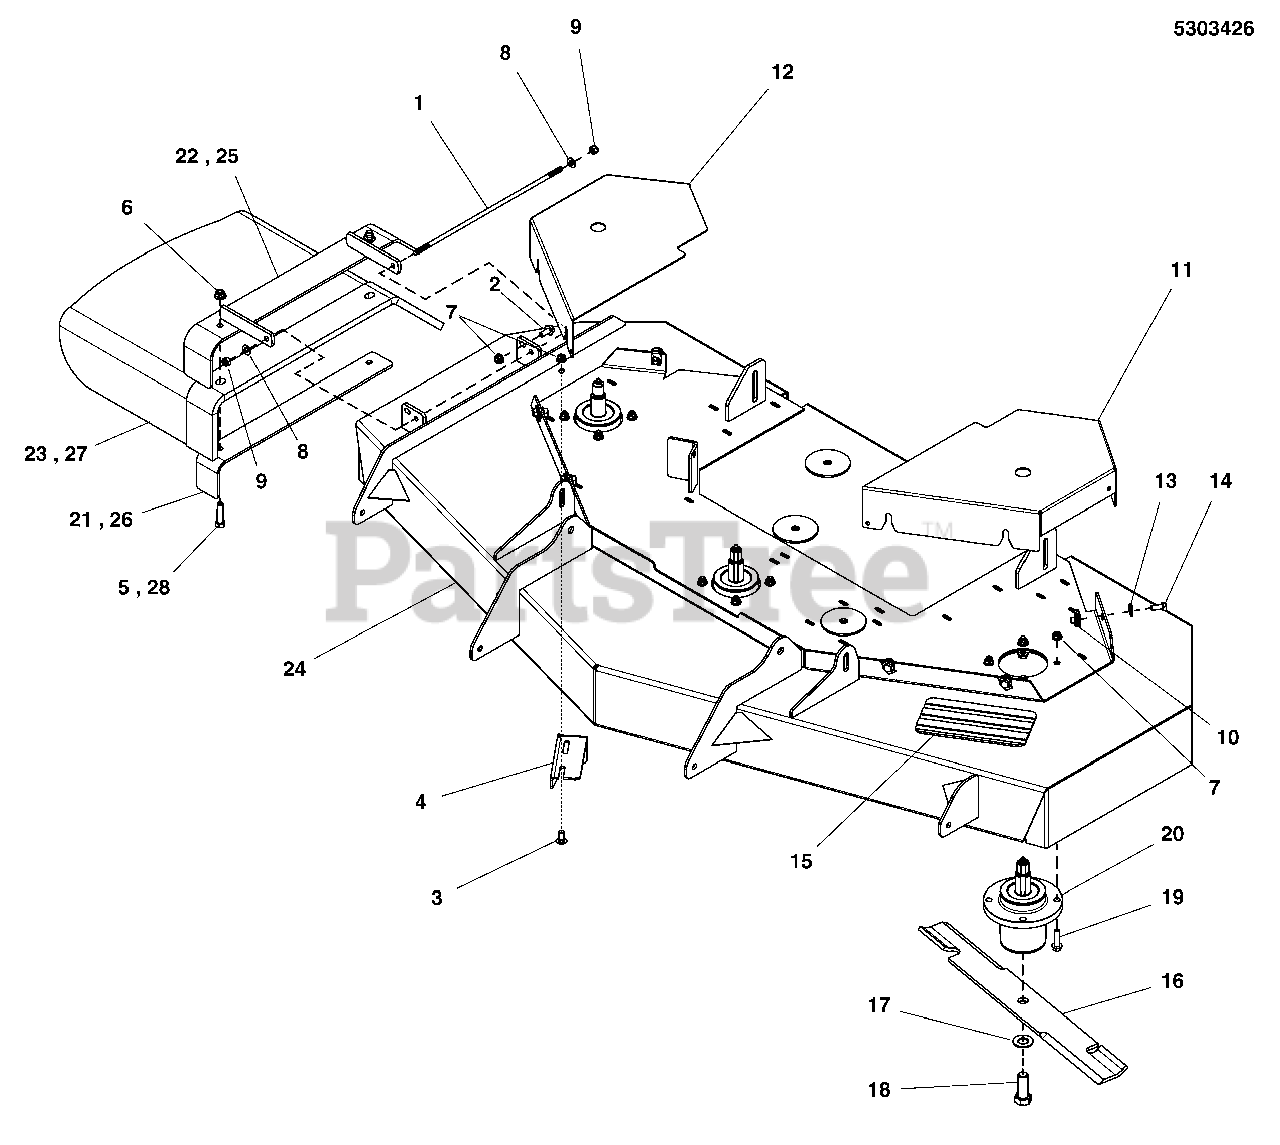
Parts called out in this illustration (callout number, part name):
1	ROD, 5/16 X 13.75, TBE, CZ
2	SCREW, Flange, Whiz-Lock, 5/16-18 X 3/4
3	BOLT, 5/16-18 X 3/4, CARRIAGE
4	PLATE, Deflector
5	BOLT, 3/8-16 X 1-1/2 GD5 YZ
6	NUT, Hex Flange, Nylock, 3/8-16
7	NUT, 5/16-18 HEX NYLOCK FLANGE
8	WASHER, 5/16 SAE
9	NUT, 5/16-24 HEX NYLON LOCK
10	BODY CLIP, 5/16-18-7GA MATERIAL
11	GUARD 61" - LH - RED
12	GUARD 61" - RH - RED
13	WASHER, 5/16 SAE
14	BOLT, 5/16-18 X 3/4 GD5
15	SAFETY WALK, 4.00 X 7.50
16	BLADE SET, .187 X 2.50 X 21.00 (3) (SV)
17	WASHER, Blade Bolt, 9/16"
18	BOLT, 5/8-11 X 1-3/4 GD8
19	BOLT, 5/16-18 X 1 1/4 FLANGE
20	ASSM, SPINDLE, LOW PROFILE
21	SUPPORT, DISCHARGE CHUTE, 48/52
22	WELD, FRAME CHUTE, 44/48/52 -SNP RED
23	CHUTE, DISCHARGE, BEND RUBBER, 44/48/52
24	DECK SHELL W/DECALS, 61, 550Z/2950 (SV)
24	DECK SHELL W/DECALS, 61, 550Z ANSI-EXP (SV)
25	WELD, MOUNT, DISCHARGE CHUTE - BLK
26	SUPPORT, DISCHARGE CHUTE - BLK
27	CHUTE, RUBBER DISCHARGE - BLK
28	BOLT, 3/8-16 X 1-1/2, CARRIAGE, GD5, CZ
